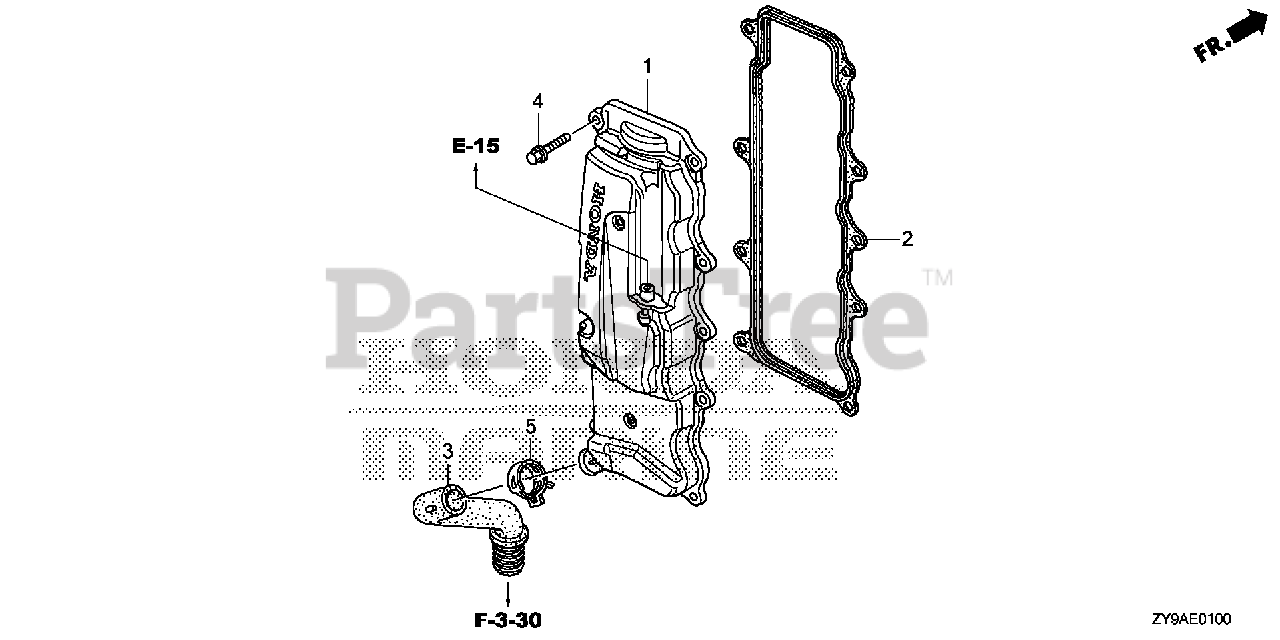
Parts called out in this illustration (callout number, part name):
1	COVER, CYLINDER HEAD
2	GASKET, HEAD COVER
4	BOLT, FLANGE (6X22)
5	CLAMP, TUBE (D29)
